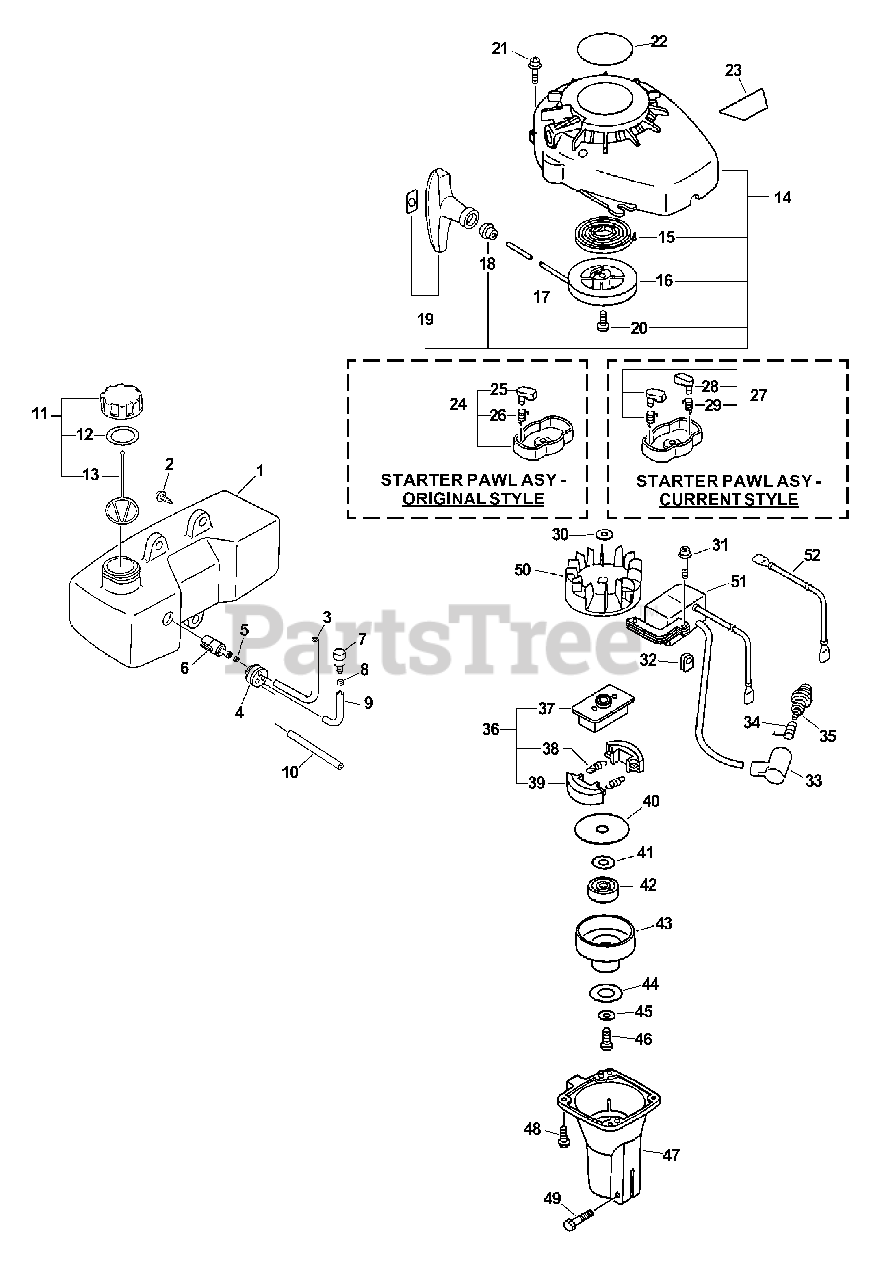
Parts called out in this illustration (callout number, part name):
1	TANK, FUEL
2	SCREW 5×15
3	PIPE, FUEL 3×5×210 BLACK
4	GROMMET, FUEL
5	CLIP 6 MM
6	FILTER, FUEL
7	VENT ASSY
9	PIPE, FUEL 3x-5x-70 BLACK
10	PIPE, FUEL 3×6×50
11	CAP ASSY, FUEL
12	GASKET, FUEL CAP
13	CONNECTOR, CAP L= 100 MM
14	STARTER ASSY
15	SPRING, RECOIL
16	REEL, ROPE
17	ROPE, STARTER 3.0×1000
18	GUIDE, ROPE
19	GRIP, STARTER
20	SCREW
21	SCREW 4×16
22	LABEL, ECHO
23	LABEL, TC-2100
24	PAWL ASSY, STARTER
25	PAWL, STARTER - BLACK
26	SPRING, RETURN
27	PAWL ASSY, STARTER
28	PAWL, STARTER - BLACK
29	SPRING, RETURN
30	WASHER, SPRING 8
31	SCREW 4×22
33	CAP, SPARK PLUG
34	TERMINAL, SPARK PLUG
35	SPARK PLUG - BPM-7Y
35	SPARK PLUG - BPMR7A
36	CLUTCH ASSY
37	HUB, CLUTCH
38	SPRING, CLUTCH
39	SHOE, CLUTCH
40	PLATE, CLUTCH
41	WASHER 10.5×18×1.6
42	BEARING, BALL 6000-2RLB
43	DRUM, CLUTCH
45	WASHER, CLUTCH
46	SCREW 6×12
47	CASE, CLUTCH
48	SCREW 4×14
49	BOLT 5
50	FLYWHEEL
51	COIL, IGNITION
52	LEAD
